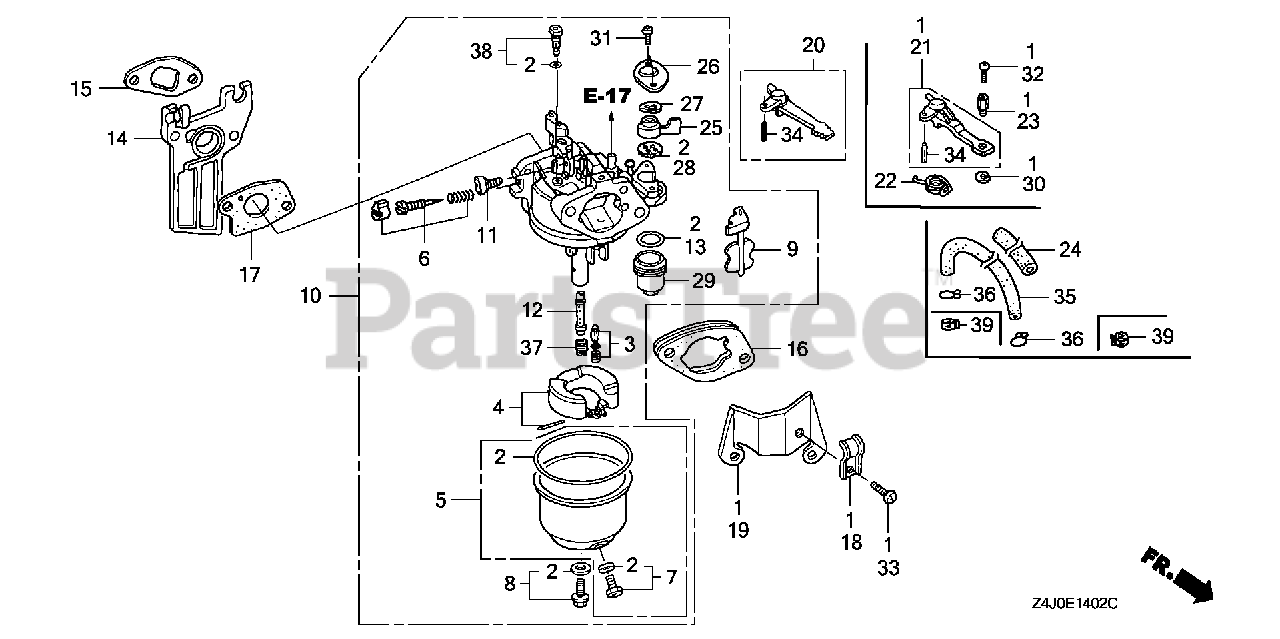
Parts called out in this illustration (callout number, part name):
2	GASKET SET
3	VALVE SET, FLOAT (CARBURETOR NO.) (SEAT NOT INCLUDED)
4	FLOAT SET
5	CHAMBER SET, FLOAT (CARBURETOR NO.)
6	SCREW SET (Honda Code 4219879). (CARBURETOR NO.)
7	SCREW SET, DRAIN (Honda Code 1672187). (CARBURETOR NO.)
8	SCREW SET B
8	SCREW SET
9	CHOKE SET
10	CARBURETOR ASSY. (BE65B B/C)
11	SCREW, THROTTLE STOP
12	NOZZLE, MAIN
13	GASKET, FUEL STRAINER CUP
14	INSULATOR, CARBURETOR
15	GASKET, INSULATOR
16	SPACER, CARBURETOR
17	GASKET, CARBURETOR
20	LEVER, CHOKE (STD)
25	LEVER, VALVE
26	PLATE, LEVER SETTING (CARBURETOR NO.)
27	SPRING, PETCOCK LEVER (CARBURETOR NO.)
28	GASKET, VALVE
29	CUP, FUEL STRAINER
31	SCREW, PAN (3X6)
34	PIN, SPRING (2X12)
37	JET, MAIN (#65)
37	JET, MAIN (#68)
37	JET, MAIN (#70)
38	JET SET, PILOT (#35)
